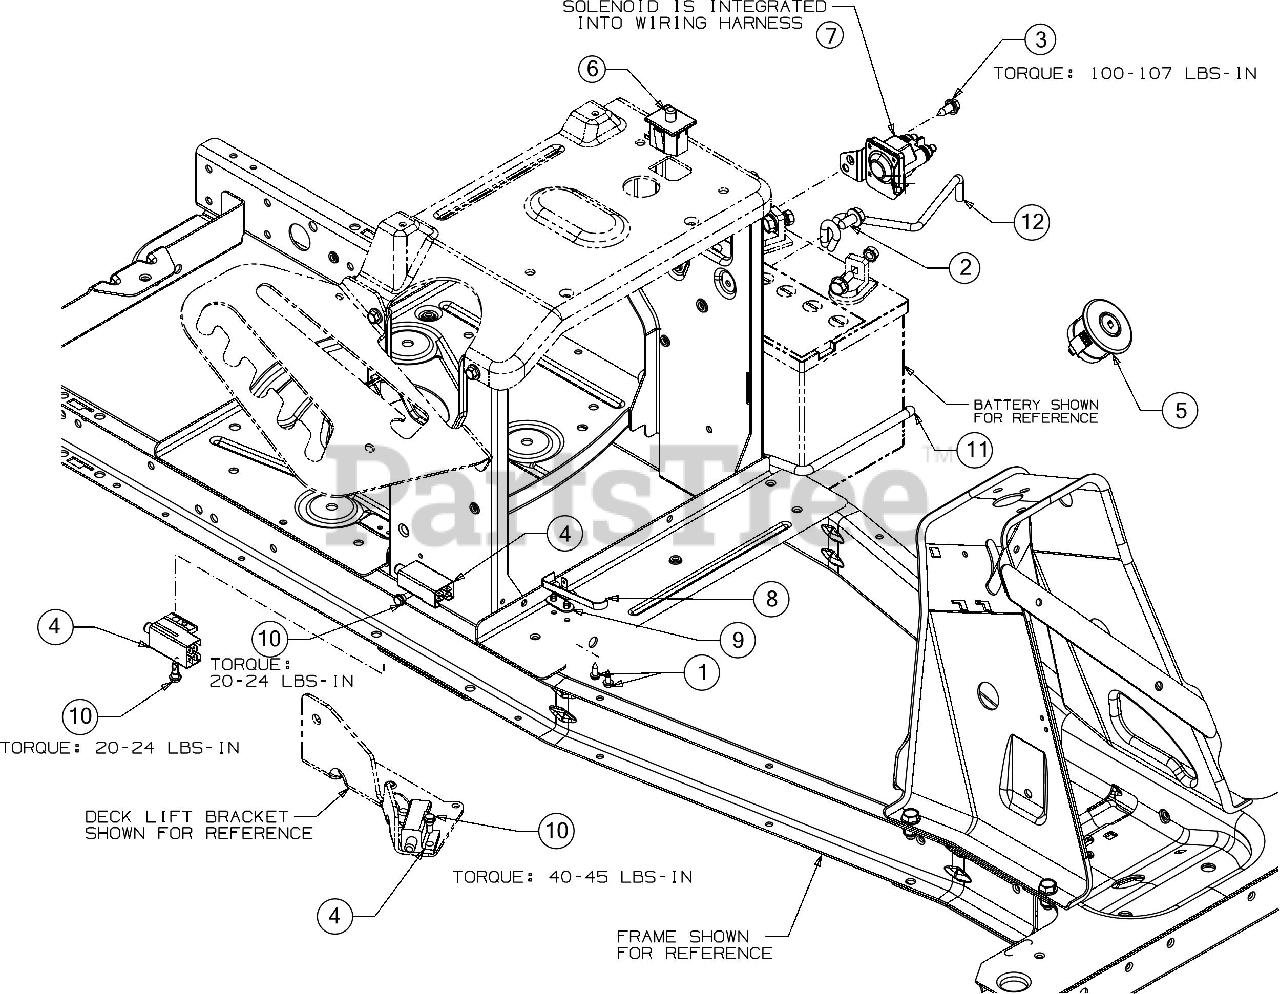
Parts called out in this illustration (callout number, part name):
1	HEX SCREW WASHER HD #8-18 x 0.500
2	SCREW 5/16-18 x .750
3	SCREW 1/4-20X.625
4	INTERLOCK SWITCH (NO/NC)
5	3 POSITION KEY SWITCH
6	SEAT SWITCH
7	HARNESS
8	SPRING SWITCH
9	INSULATOR PLATE
10	SHOULDER SCREW
11	BATTERY TRAY ROD
12	BATTERY HOLD DOWN ROD
